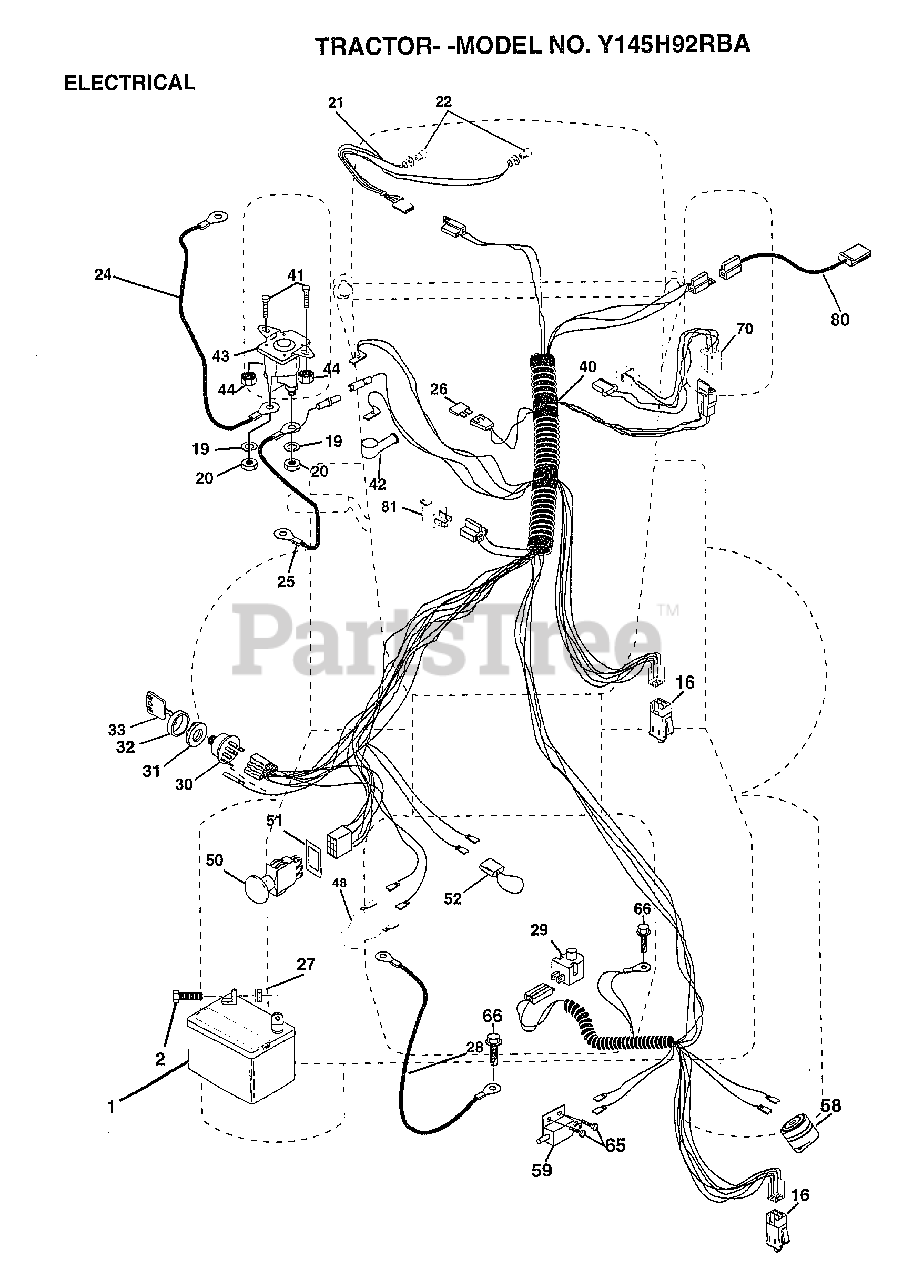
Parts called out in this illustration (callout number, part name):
2	BOLT LT
16	SWITCH INTERLOCK
20	NUT
21	HARNESS.ASM.LIGHT W/4152J
22	HEADLAMP BULB
24	"CABLE T, BATTERY"
25	CABLE.BATTERY.CRD
26	FUSE.15 AMP
27	NUT
28	"CABLE.GRD.6GA/18""BLACK"
29	SWITCH.PLUNGER
30	SWITCH IGN 4POS
31	NUT IGNITION
32	COVER KEY SWITCH
33	KEY
40	HARNESS.IGN.CRD.ELECT
41	BOLT HXHD FIN
44	NUT HXKEP 1/4X20
48	ADAPTER AMMETER
50	PTO SWITCH.RED
51	RING RETAIN PTO
52	PROTECTION LOOP
59	SWITCH.FBI.CRD
65	SCREW
66	SCREW LT
70	HARNESS.ENGINE
80	HARNESS.CLUT.EVX.
81	RELAY ASSY T
